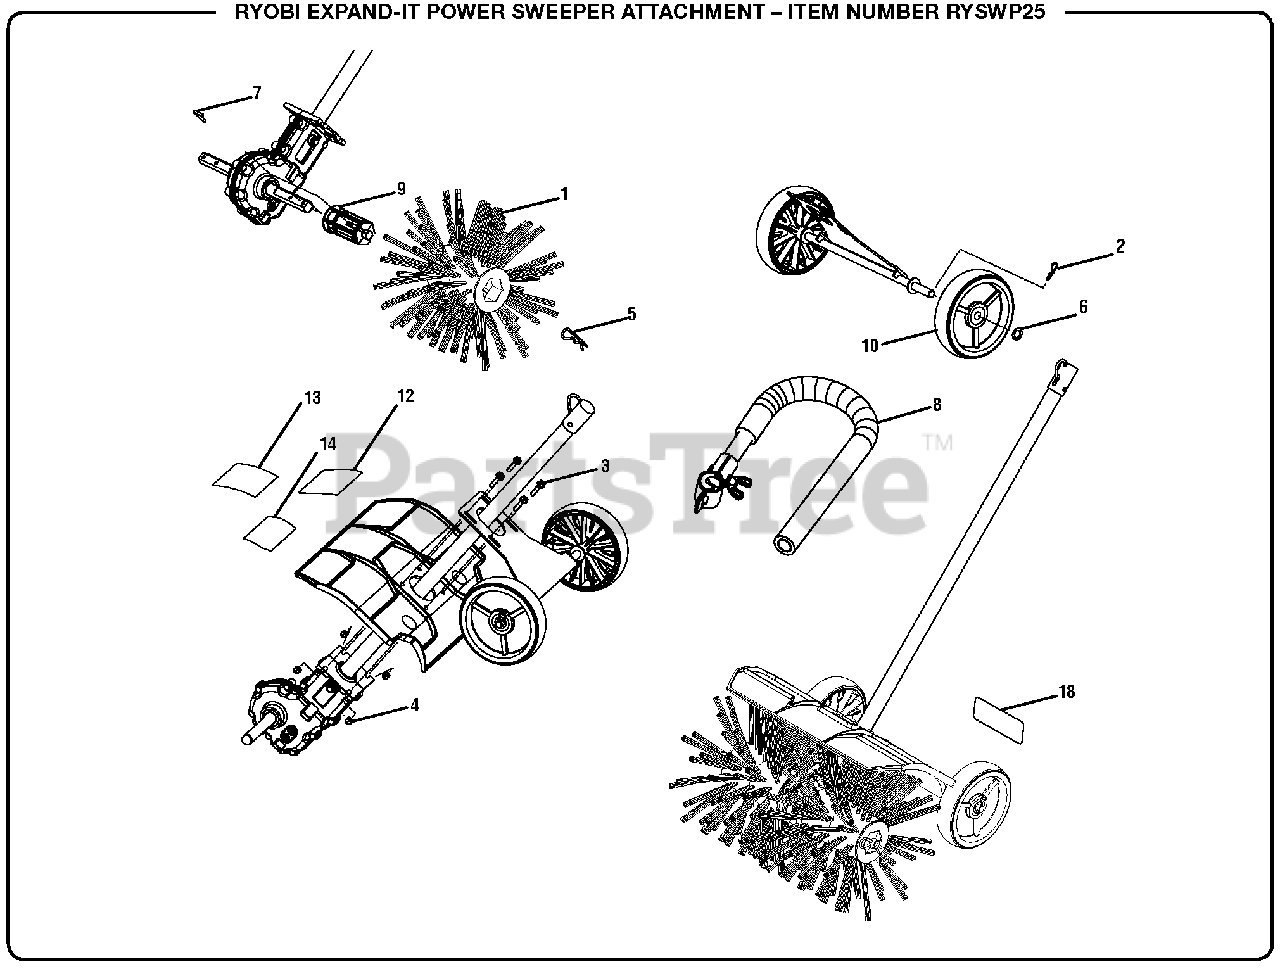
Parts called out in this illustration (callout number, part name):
2	Hitch Pin
3	Bolt (M6 x 25 mm, Hex Hd.)
4	Lock Nut (M6)
5	Hitch Pin (M3)
6	Washer (ID13.5 x OD20 x 1t)
7	Holding Pin
8	J-Bar Handle
9	Brush Assembly Adapter
10	Wheel (150 mm)
11	Icon Warning Label
12	Left Power Label
13	Center Expand-It Label
14	Right Sweeper Label
